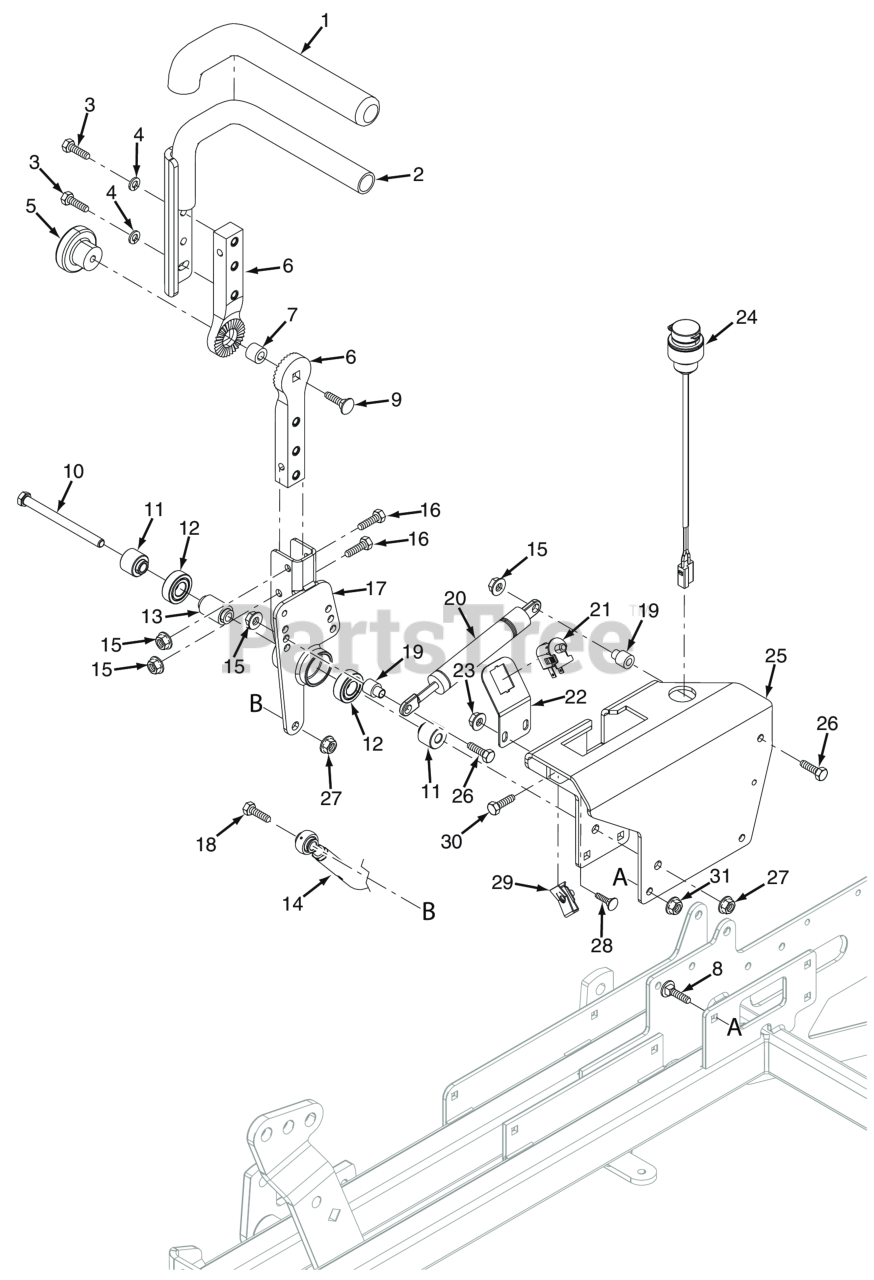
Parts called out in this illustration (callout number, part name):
1	Grip, Control Handle
2	Handle Bar w/Grip - RH
2	Handle Bar w/Grip - LH
3	Bolt, Heax Head 5/16-18 x 1" (48V / 52V)
4	Lockwasher, 5/16 (.317 x .586 x .078) Helical Spring
5	Knob, Control Handle
6	Pivot, Control Lever
7	Spacer, Rubber
8	Bolt, 5/16-18 x .75 RHSN Carriage
9	Bolt, RDHD Carr. 3/8-16 x 1-1/2 (52" & 61")
10	Bolt, 3/8 - 16 x 4 - 1/2" Hex Head
11	Spacer, Controls
12	BEARINGS, BALL, NEUTRAL RETURN
13	Spacer, Bearing
14	Nut, 3/8-24 UNF-2B LH Thread
14	Nut, 3/8-24 UNF R.H. Thread
15	HEX NUT, ELASTIC STOP LOCK, 5/16-18
16	Bolt, Hex Head 5/16-18 x 1-1/2" - Front
18	Bolt, Hex Head, 3/8-16 x 1-1/2"
19	Spacer, Pump Dampener
20	Damper, Steering
21	Switch, Interlock, Normally Open
22	Bracket, Operator Presence Switch
23	Nut, Flanged Elastic Stop 1/4-20
24	Power Plug, 12V
25	Control Weldment w/ Decal
26	Bolt, Hex Head 5/16-18 x 1-1/2" (Right Front Engine Mounting, Briggs and Kohler Only)
27	HEX NUT, ELASTIC STOP LOCK, 3/8-16
28	Serr. Fl. Hex Head CPSCR, 1/4-20 x 3/4"
29	U-Nut, 3/8-16 (short)
30	Bolt, Hex Head 3/8-16 x 1-1/4" with Thread Lock Patch
31	Nut, Serrated Flange 5/16-18 (Right Front Engine Mounting, Briggs and Kohler Only)
